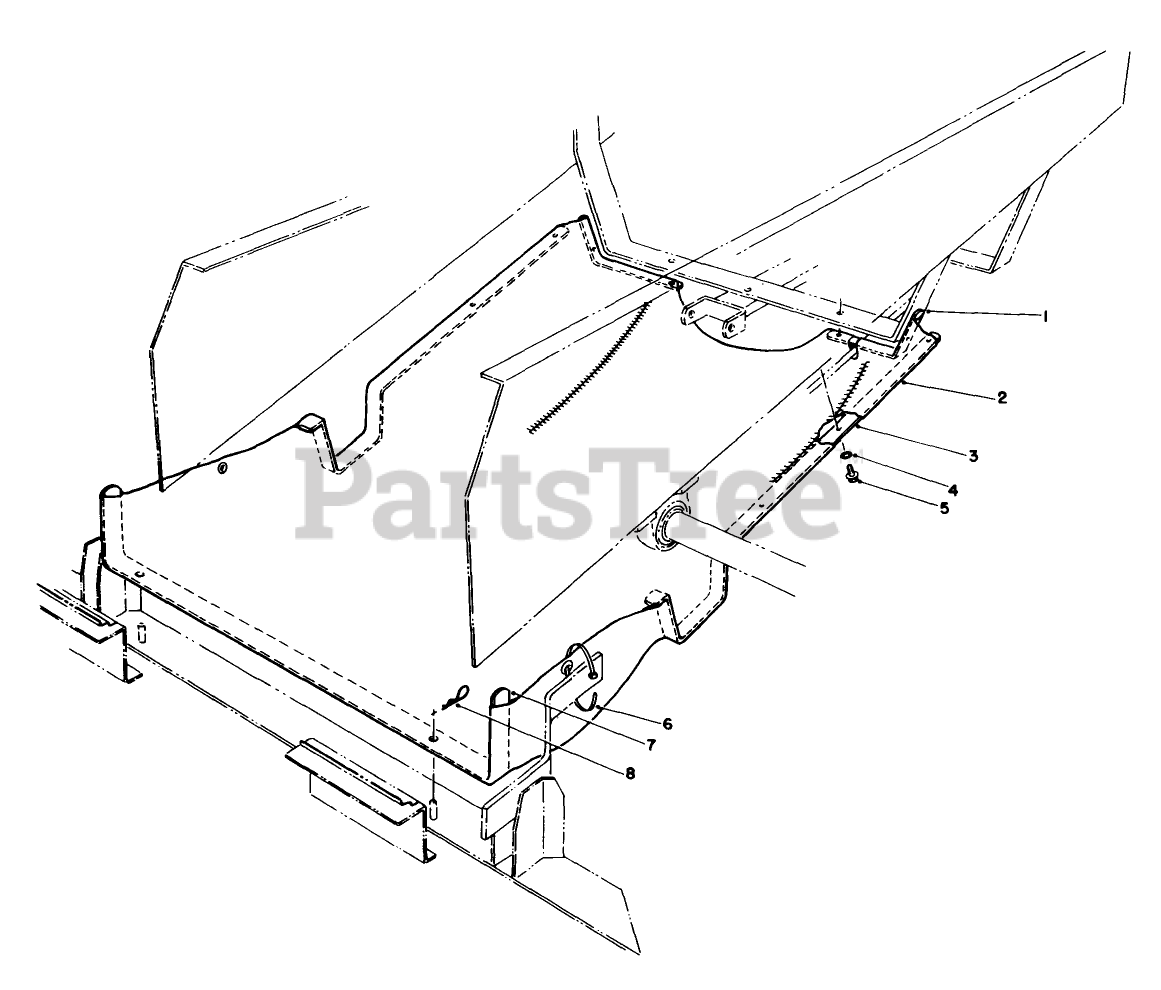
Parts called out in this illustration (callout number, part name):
1	SHIELD BRACKET R
2	CLOTH SHIELD
3	Support-Side
4	WASHER-LOCK
5	SCREW-HWH
6	TIE-CABLE
7	DECK SHIELD SUPPORT R
8	PIN-COTTER
